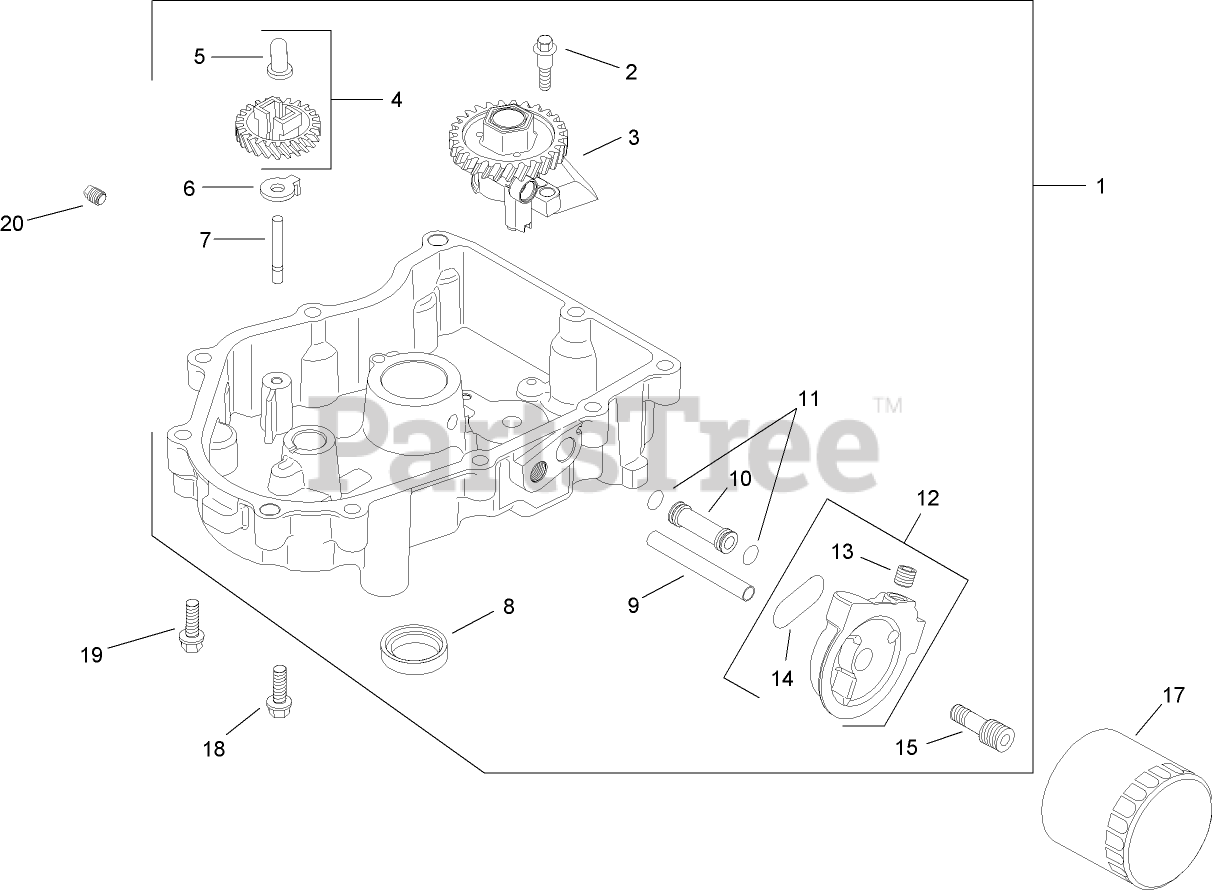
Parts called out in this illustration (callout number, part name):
1	OIL PAN ASM (INCLUDES 2-15)
2	SCREW-SHOULDER, THD FRM (M6x1.0x26.5)
3	Oil Pump ASM
4	GOVERNOR GEAR KIT W/PIN (INCLUDES 5)
5	PIN-REGULATING, GOVERNOR
6	TAB-LOCKING
7	SHAFT-GEAR, GOVERNOR
8	SEAL-OIL (P-T-O END)
9	TUBE-FEED, OIL (FILTER TO PAN)
10	TUBE-FEED, OIL (PAN TO FILTER)
11	O-RING
12	ADAPTER OIL FILTER KIT (INCLUDES 13-14)
13	PLUG-PIPE, COUNTERSUNK (1/8)
14	O-Ring-Oil Filter Adapter
15	NIPPLE-FILTER, OIL
17	FILTER-OIL
18	SCREW-FLANGE (M8X1.25X45)
19	Screw-HF (M8x1.25x45)
20	PLUG-PIPE, SQ HD (3/8)
